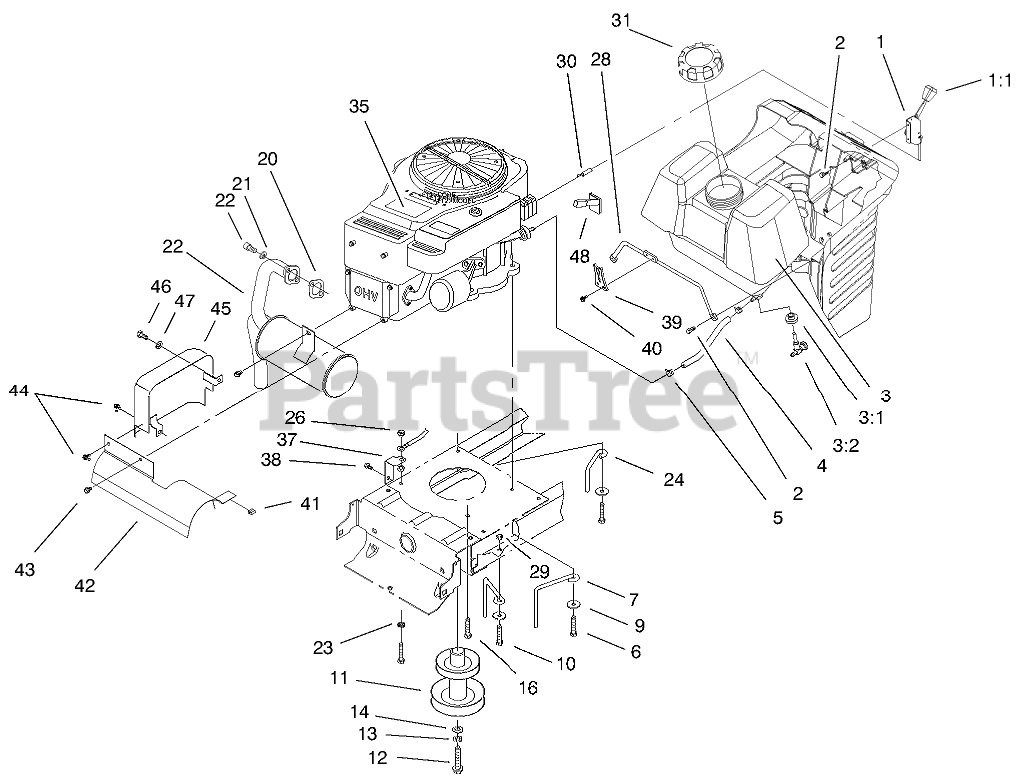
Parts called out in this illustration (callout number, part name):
1	THROTTLE CONTROL ASM
2	SCREW-SPECIAL
3	GAS TANK ASM
3:1	BUSHING
3:2	VALVE-FUEL
4	HOSE-FUEL
5	CLAMP-HOSE
6	SCREW-HH
7	GUIDE-BELT, ENGINE
9	WASHER-PIVOT
10	SCREW-HH
11	PULLEY-ENGINE ASM
12	SCREW-HH
13	WASHER-LOCK
14	WASHER-FLAT
15	MUFFLER-EXHAUST
16	SCREW-HWH, TAPTITE
20	GASKET-EXHAUST
21	WASHER-LOCK
22	SCREW-HSH
23	WASHER-LOCK
24	GUIDE-BELT, RH
26	NUT-KEPS
28	ROD-TANK, GAS
29	NUT-LOCK, NI
30	THROTTLE CABLE ASM
31	GAS CAP ASM
35	DECAL - ENGINE
37	BRACKET-GROUND
38	SCREW-HWH
39	LATCH-HOOD
40	SCREW-HWH
41	CLIP-TINNERMAN
42	SHIELD-MUFFLER
43	SCREW-HWH
44	SCREW-HWHTF
45	HEAT SHIELD ASM
46	SCREW-HH
47	WASHER-LOCK
48	Reducer-Throttle Rpm (Only On: 71220)
